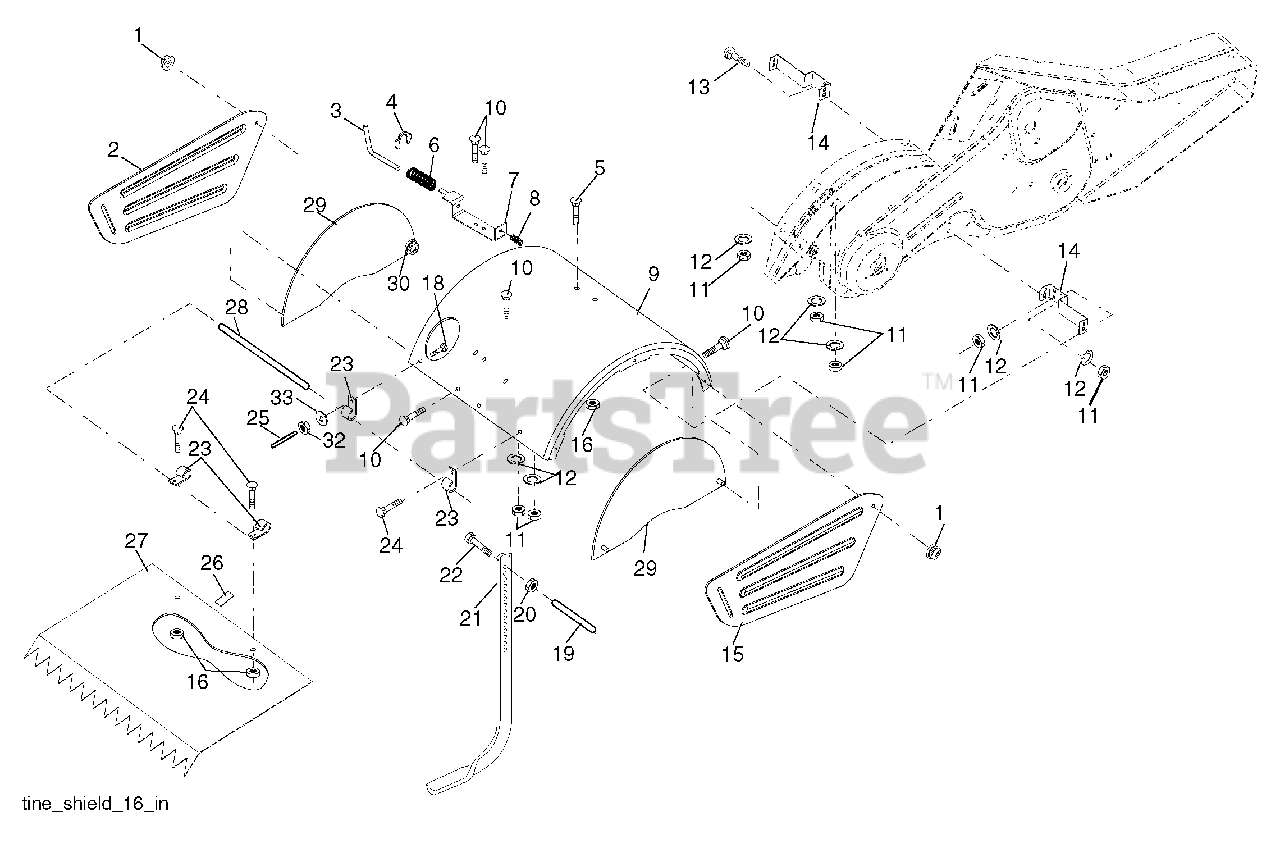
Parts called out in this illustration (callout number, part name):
1	Nut, Lock Hex Flange 5/16-18
2	Shield, Side, Outer L. H.
3	Pin, Stake, Depth
4	Ring, Klip
5	Bolt 5/16-18 unc x 1
6	Spring
7	Bracket, Latch
8	Spring, Depth Stake
9	Shield, Tine
10	Bolt 5/16-18 x 3/4 ZNC
11	Nut, Hex 5/16-18
12	Washer, Lock 5/16
13	Bolt, Carriage 5/16-18 x 1-1/4
14	Bracket, Shield Tine
15	Shield, Side, Outer R.H.
16	Nut, Hex Flange 1/4-20 unc
18	Bolt, Carriage 1/4-20 x 1-1/4 Gr. 5
19	Grip
20	Nut, Hex 3/8-16
21	Stake, Depth
22	Bolt, Hex 3/8-16 x 2
23	Hinge
24	Bolt, Carriage 1/4-20 x 1/2 Gr. 5
25	Cap, Vinyl
26	Pad, Idler
27	Shield, Leveling
28	Pin, Hinge
29	Shield, Side
30	Locknut, Flange 5/16-18
32	Nut Fin Hex 1/4-20 unc
33	Washer Lock Hvy Helical 1/4
